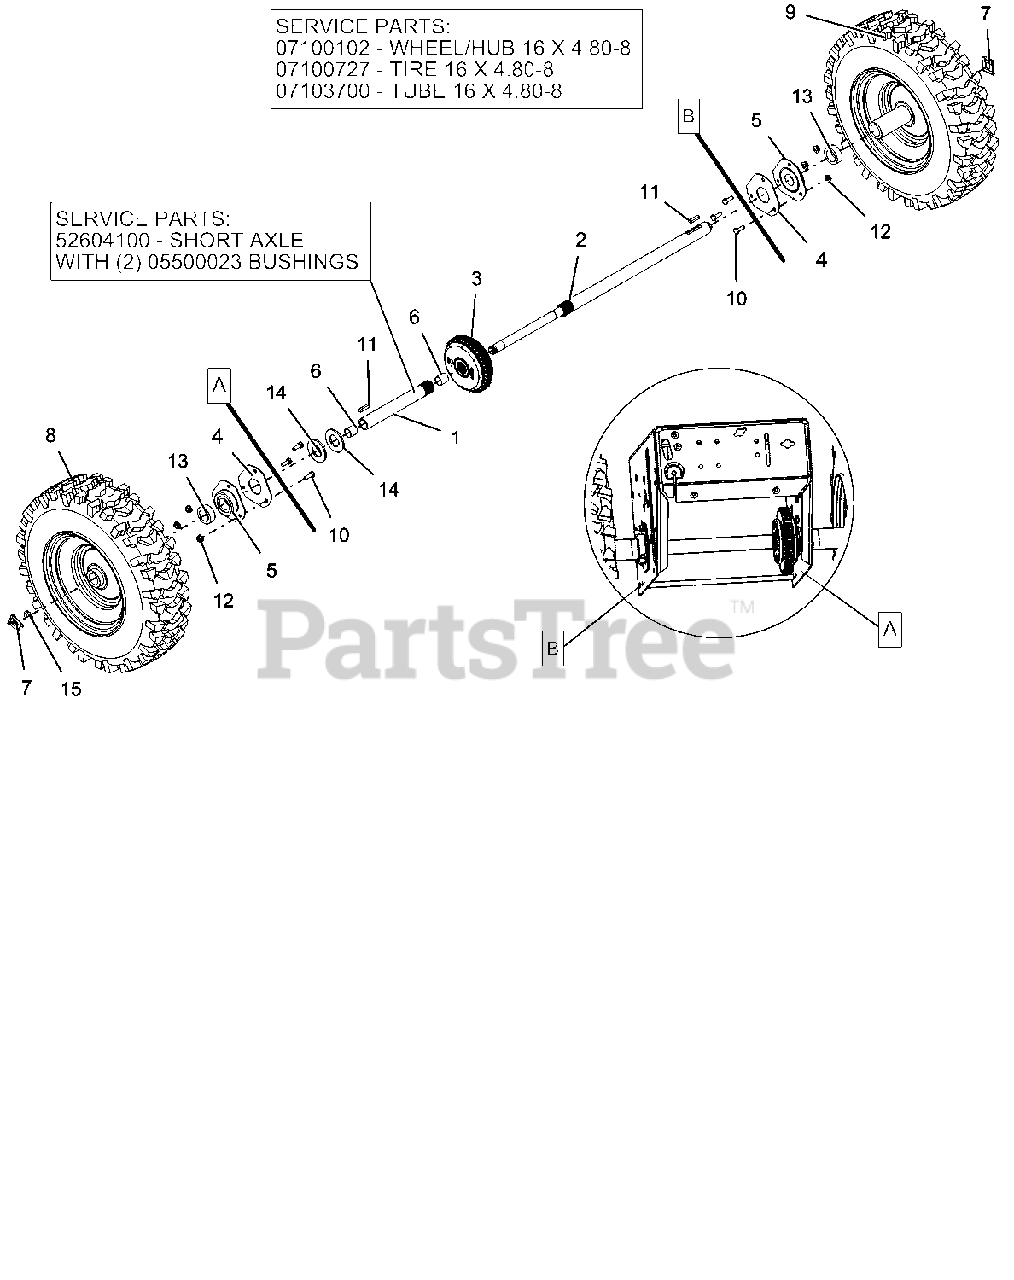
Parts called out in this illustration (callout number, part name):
1	BUSHING, POLYLINER-.50 SPLIT
1	AXLE, SHORT-PRO AUTO DIFF
1	AXLE, SHORT-AUTO W/BUSHINGS
2	AXLE, LONG-PRO AUTO DIFF
3	DIFFERENTIAL, AUTOMATIC
4	PLATE, BEARING SPACER
5	BRG-FLG 1.003/1.000 3 BOLT
6	BSHG-SLV .706X.764X.75 BRZ
7	CLIP, SNAP .625 DIA
8	TIRE/WHEEL,RH 16X4.8-8 DIFF T2
9	TIRE/WHEEL,LH 16X4.8-8 DIFF T2
10	@BLT-HEX .25-20X.75 GR5 YWZC
11	KEY-RECT .25X.188X1.00
12	@NUT-LK-CTR-FLG .25-20 YWZC
13	SPACER, PRO AXLE BEARING
14	WSHR-FL-STL- 1.062X2.0X.134 YZ
15	RG-RTNG-EXT .625X.042
16	HUB, WHEEL - 16X4.8-8 DIFF
17	TIRE, 4.80-8 K478
18	TUBE
